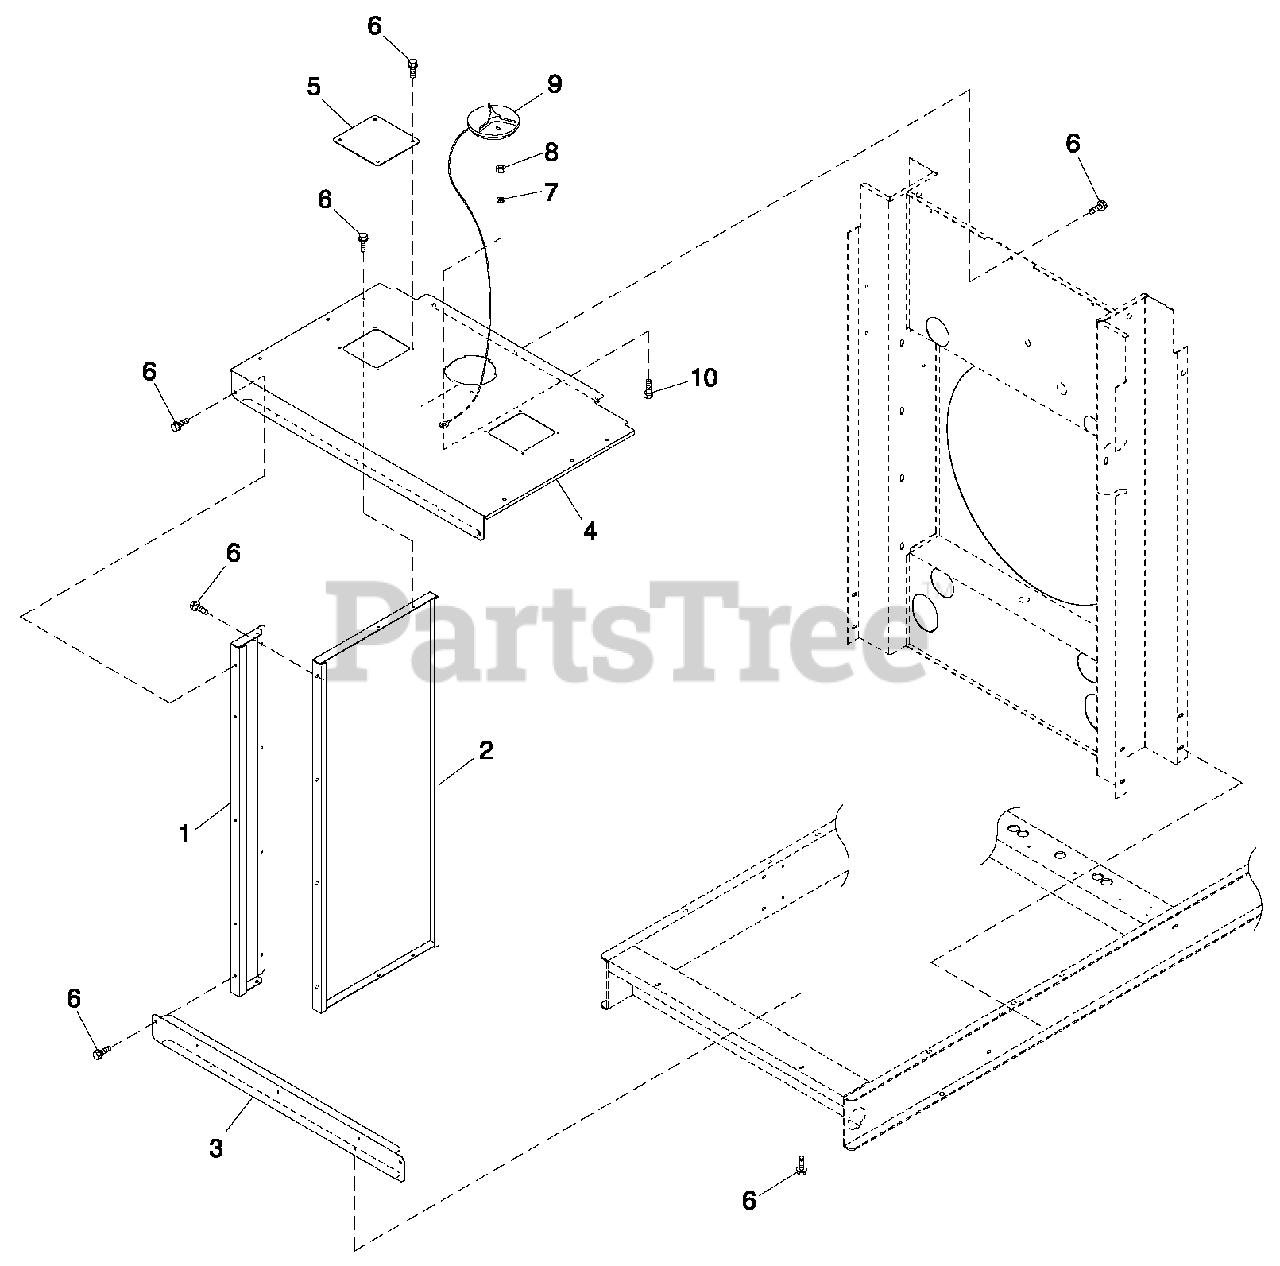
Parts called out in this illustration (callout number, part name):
1	PANEL C3 FRONT SIDES
2	PANEL C3 REAR SIDES
3	PANEL LOWER FRONT
4	PANEL C3 TOP
5	ACCESS COVER 160 X 170 GALV
6	SCREW THF M6-1 X 16 N WA Z/JS
7	WASHER LOCK M6-1/4
8	NUT HEX M6 X 1.0 G8 YEL CHR
9	ASSY ACCESS COVER
10	SCREW HHC M6-1.0X 16 G8.8
